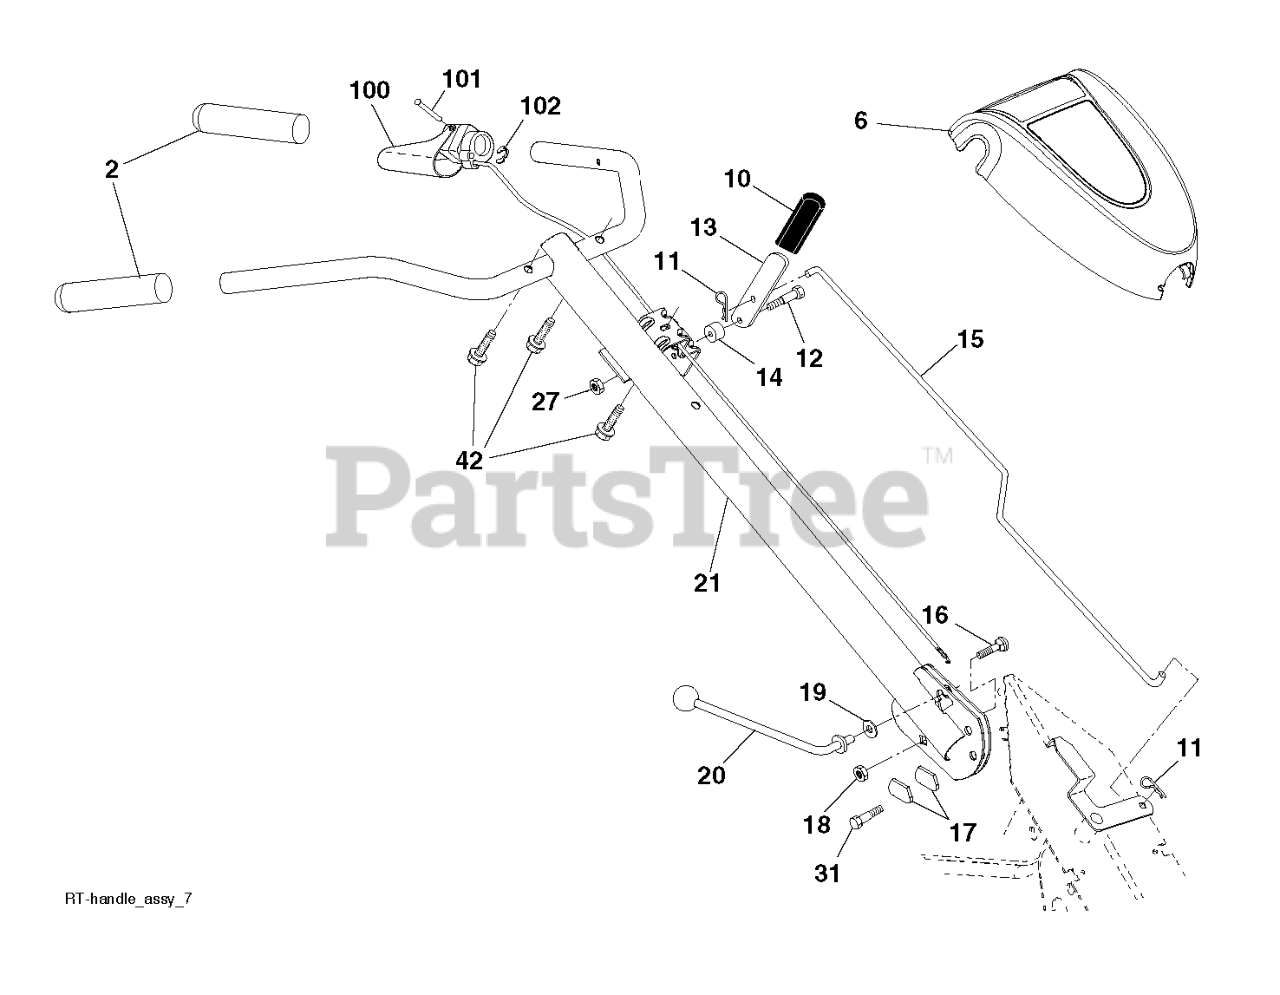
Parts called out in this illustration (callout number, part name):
2	GRIP.1X5.06
6	CONSOLE HUSQVARNA W/O THROTTLE
10	GRIP HANDLE TILLER RED
11	RETAINER M
12	SHOULDER BOLT ST
13	HANDLE
14	GROMMET.RUBBER.CRT.TILLER
15	ROD SHIFT RT UNIVERSAL
16	BOLT D
17	LOCK.HANDLE.CRT
19	WASHER CRT
20	LEVER.LOCK.CRT
21	HANDLE.ASM.HUSQ/P.PRO.GREY
27	NUT T
31	BOLT.PIVOT
42	SCREW.#10 X 0.750.BOS
100	CONTROL.ASSEMBLY.TINE.TILLER
101	PIN, PIVOT
102	RETAINING.RING.#5103-25
